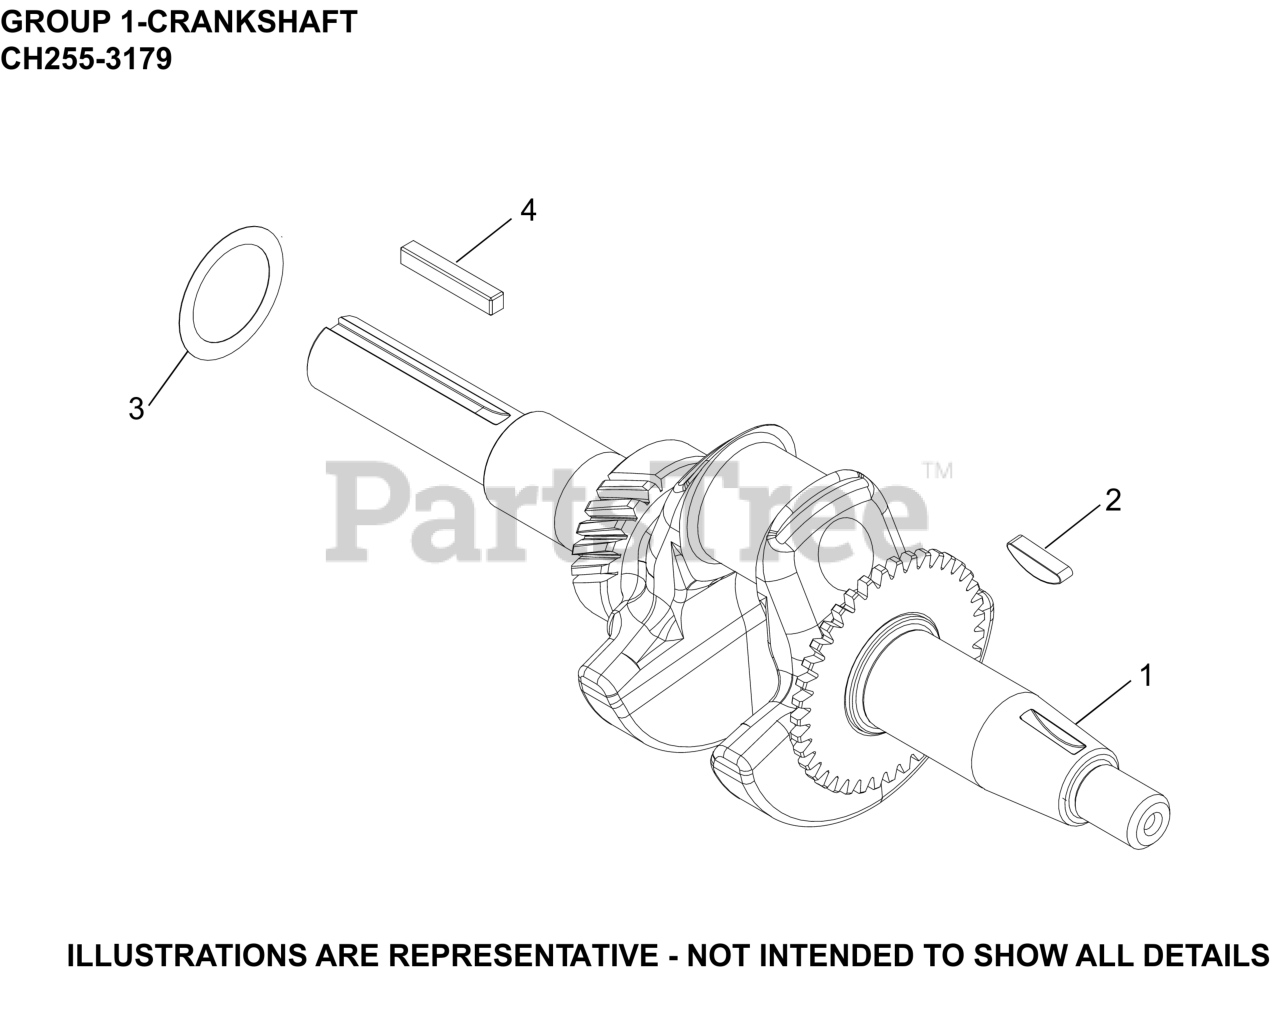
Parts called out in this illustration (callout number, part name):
1	CRANKSHAFT, ASSEMBLY
2	KEY, FLYWHEEL
3	KIT, THRUST SHIM
4	KEY, SQUARE
